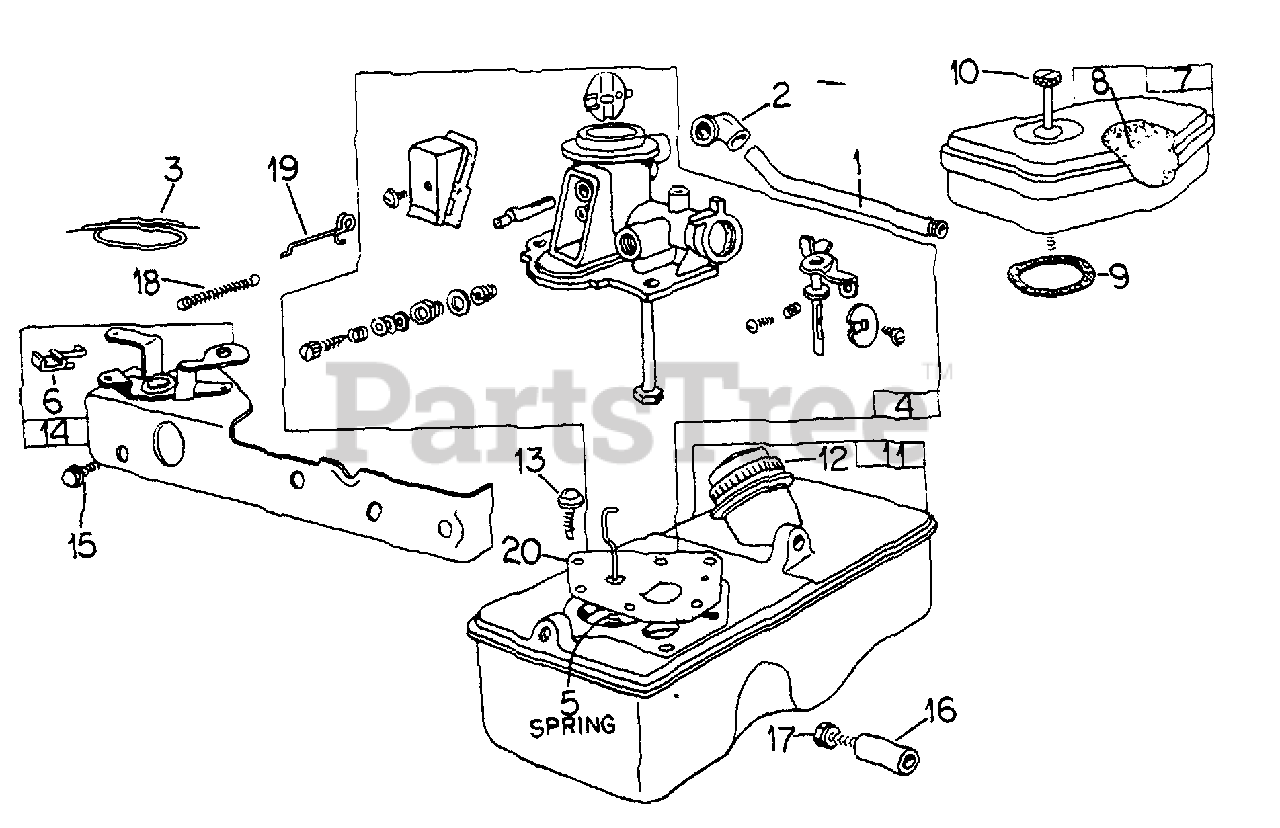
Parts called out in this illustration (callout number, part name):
1	TUBE, BREATHER
2	GROMMET, BREATHER TUBE
3	CABLE, GROUND WIRE
4	CARBURETOR ASSY
5	SPRING, DIAPHRAGM
6	SWITCH, STOP
7	CLEANER ASSY, AIR
8	ELEMENT, AIR CLEANER
9	GASKET, AIR CLEANER MOUNTING
10	SCREW, AIR CLEANER
11	TANK ASSY, FUEL
12	CAP, FUEL TANK
13	SCREW, FUEL TANK MOUNTING
14	PLATE, CARBURETOR CONTROL
15	SCREW, CONTROL PLATE TO TANK
16	BUSHING, FUEL TANK SPACER
17	SCREW, FUEL TANK TO STARTER MOTOR
18	SPRING, GOVERNOR
19	SPRING, GOVERNOR LINK
20	DIAPHRAGM, CARBURETOR
